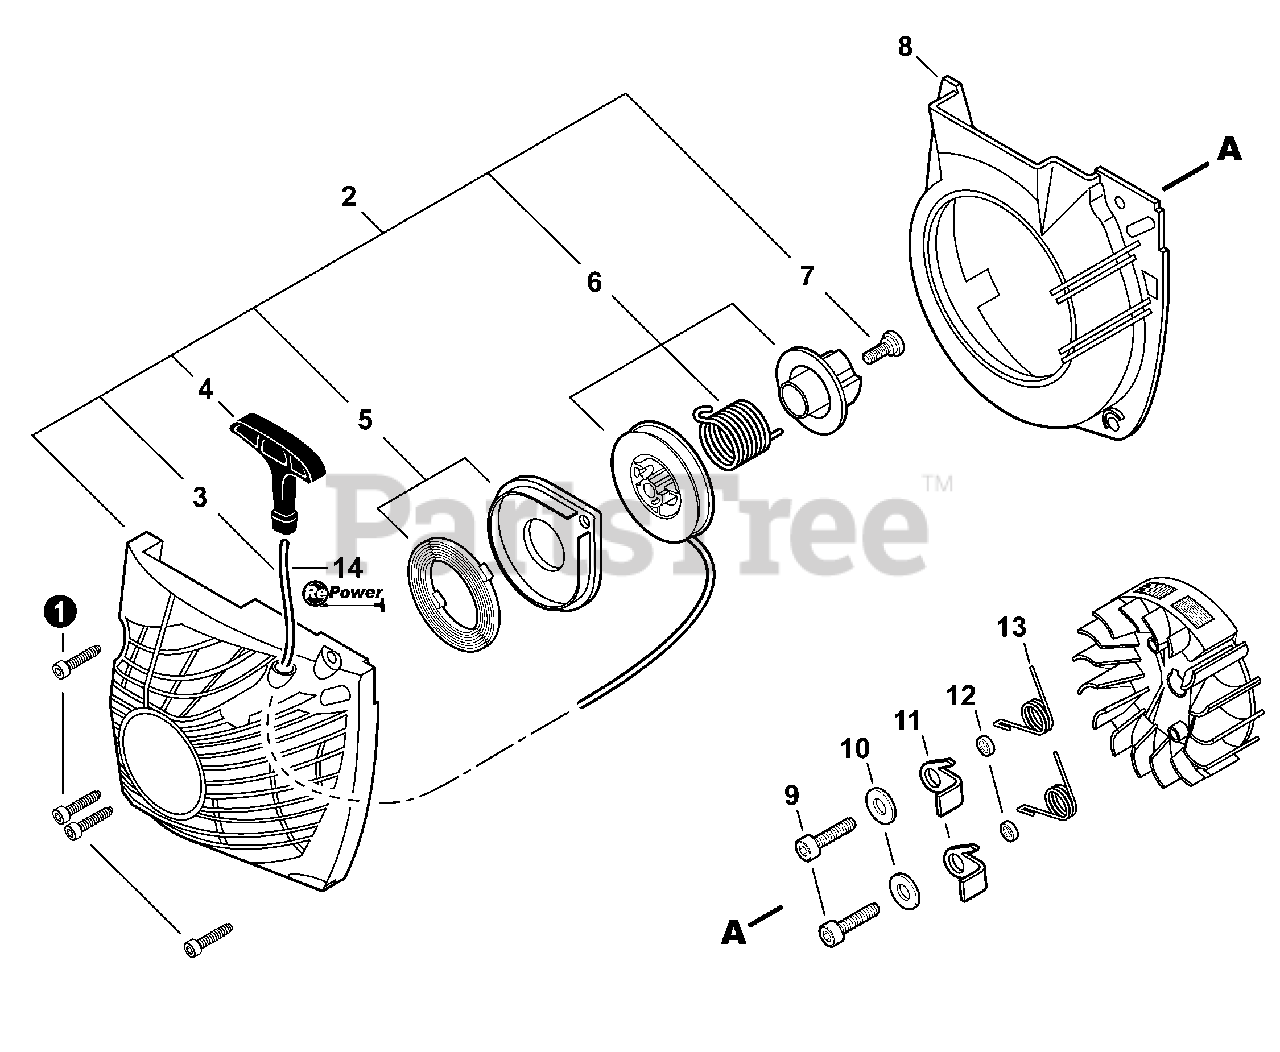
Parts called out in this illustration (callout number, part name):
1	SCREW TAPPING 5×20
2	STARTER ASSY, RECOIL - I-START
3	ROPE, STARTER 3.5×900
4	GRIP, STARTER
5	SPRING SET, RECOIL
6	REEL KIT, ROPE
7	SCREW
8	COVER, FAN
9	BOLT 5×14
10	WASHER 5.5×12×0.8
12	SPACER 5.2×8×2.1
13	SPRING, TORSION
14	BULK STARTER ROPE - Ø 3.5 MM×61 M
